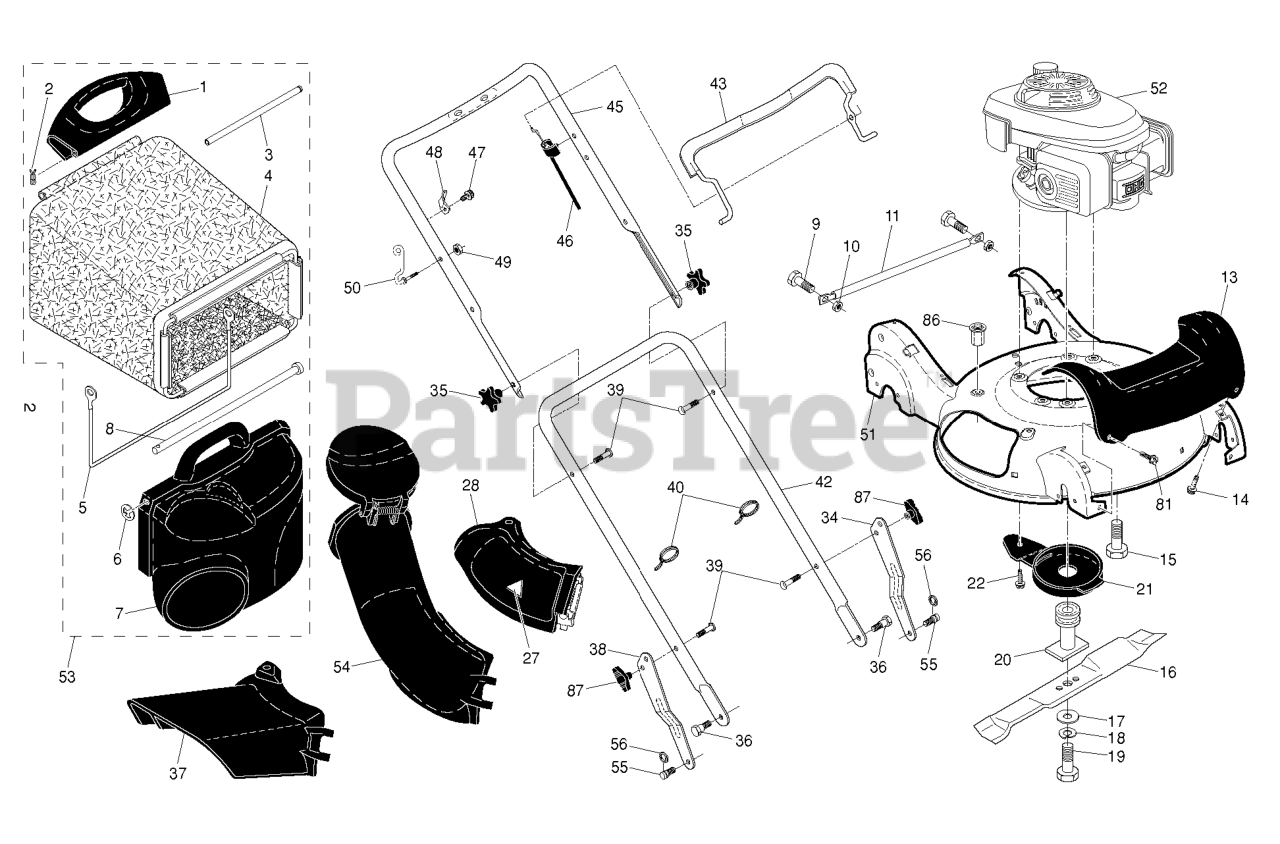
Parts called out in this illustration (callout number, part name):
1	HANDLE.GRASSBAG.REAR.H-GRAY
2	COTTER PIN (3 2)(2 2MC)
3	ROD.REAR.HANDLE.YELLOW
5	FRAME, GRASSBAG
7	DOOR, GRASSBAG
8	ROD, PIVOT
10	LOCKNUT.NYLOC.1/4-20
11	TUBE, REAR SKIRT
13	COVER.FRONT.21.HV.H-GRAY
14	SCREW, HEX WASHER HEAD
15	BOLT 3/8-16X1-1/8
16	Blade, 21"
17	WASHER,HARDEN
18	LOCKWASHER
19	BOLT.HD.HEAD.3/8-24X2.50 (2 2)
20	ADAPTER.BLADE
21	DEBRIS SHEILD
22	SCREW 1/4X20
27	DECAL.INTERNATIONL.CUTFINGER
34	ADJUSTMENT BRACKET, LOWER LH
35	KNOB.HANDLE.PLASTIC.STAR.BLACK
36	SCREW.5/16X.680.TRIM.H
38	BRACKET.ADJ.LOWER.HDL.RT.GREY
39	BOLT, HANDLE 5/16-18X1.75
40	TIE GUIDE
42	HANDLE.LOWER.GREY
43	BAIL.OVER.MOLD.ERGO.MZR.ORANGE
45	HANDLE.UPPER.3.POS.BS.AW2.GREY
46	CABLE.MZR.50.SNAP-IN
48	BRACKET.UPSTOP.RT
49	NUT
50	GUIDE.ROPE.WALK.MOWER
53	Grassbag Assembly, Complete
55	STUD.SHOULDER.T45.BZP
56	E-RING 7/16 RE
81	SCREW.HWH.13-16-5.8.BZP
87	KNOB, DEFLECTOR
